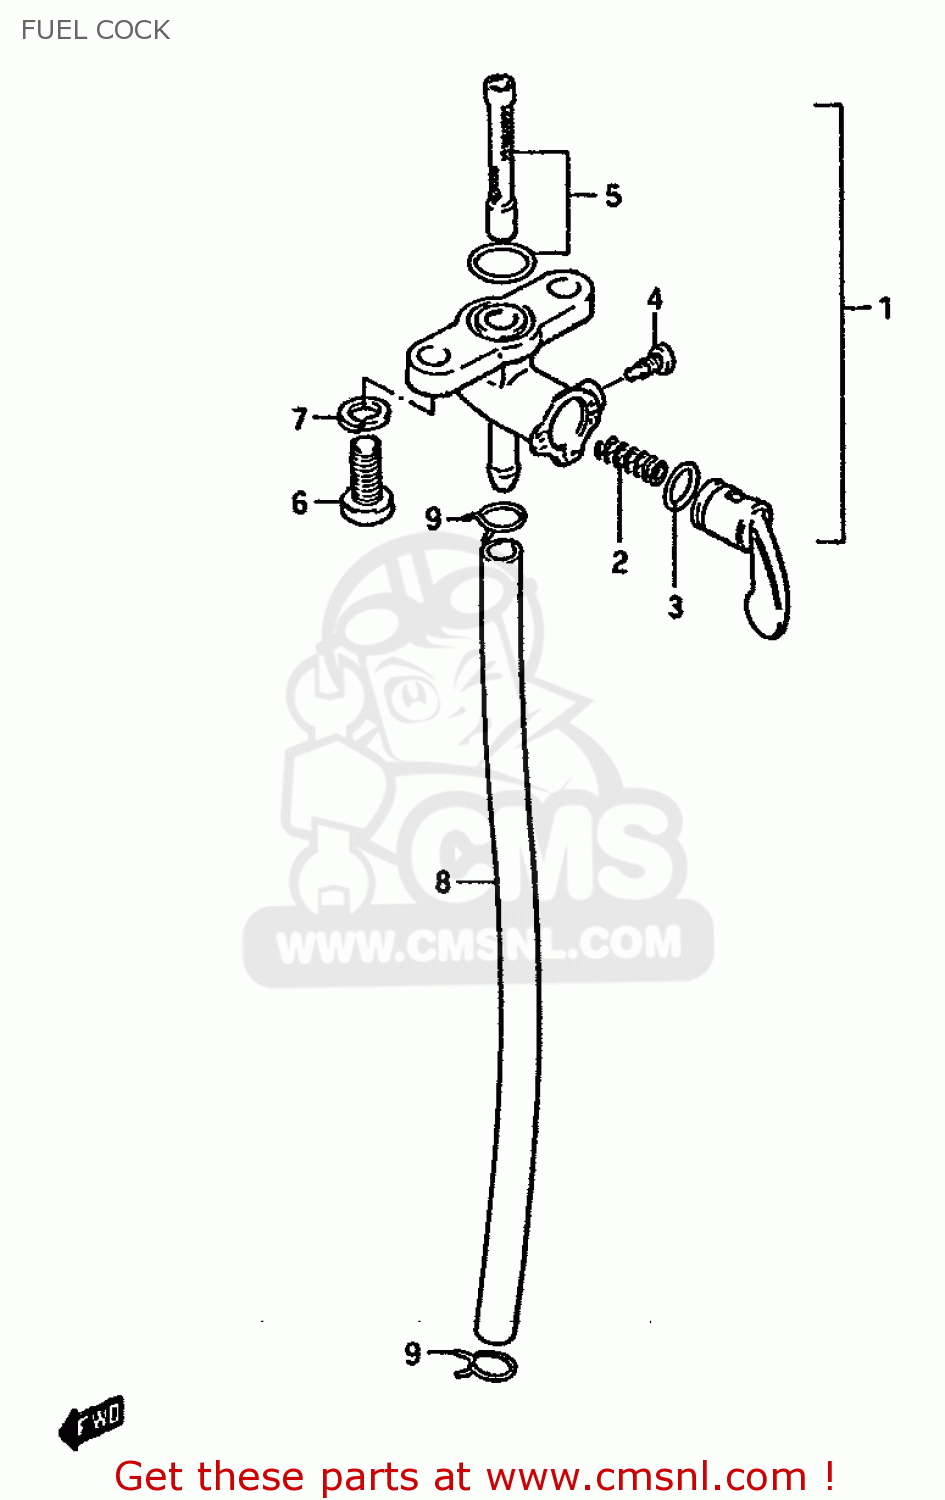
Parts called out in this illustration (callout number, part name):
1	COCK ASSY,FUEL
2	SPRING,FUEL COCK VALUE
3	O RING,LEVER
4	SCREW
5	FILTER SET FUEL
6	SCREW
7	WASHER,LOCK
8	HOSE
9	CLIP
